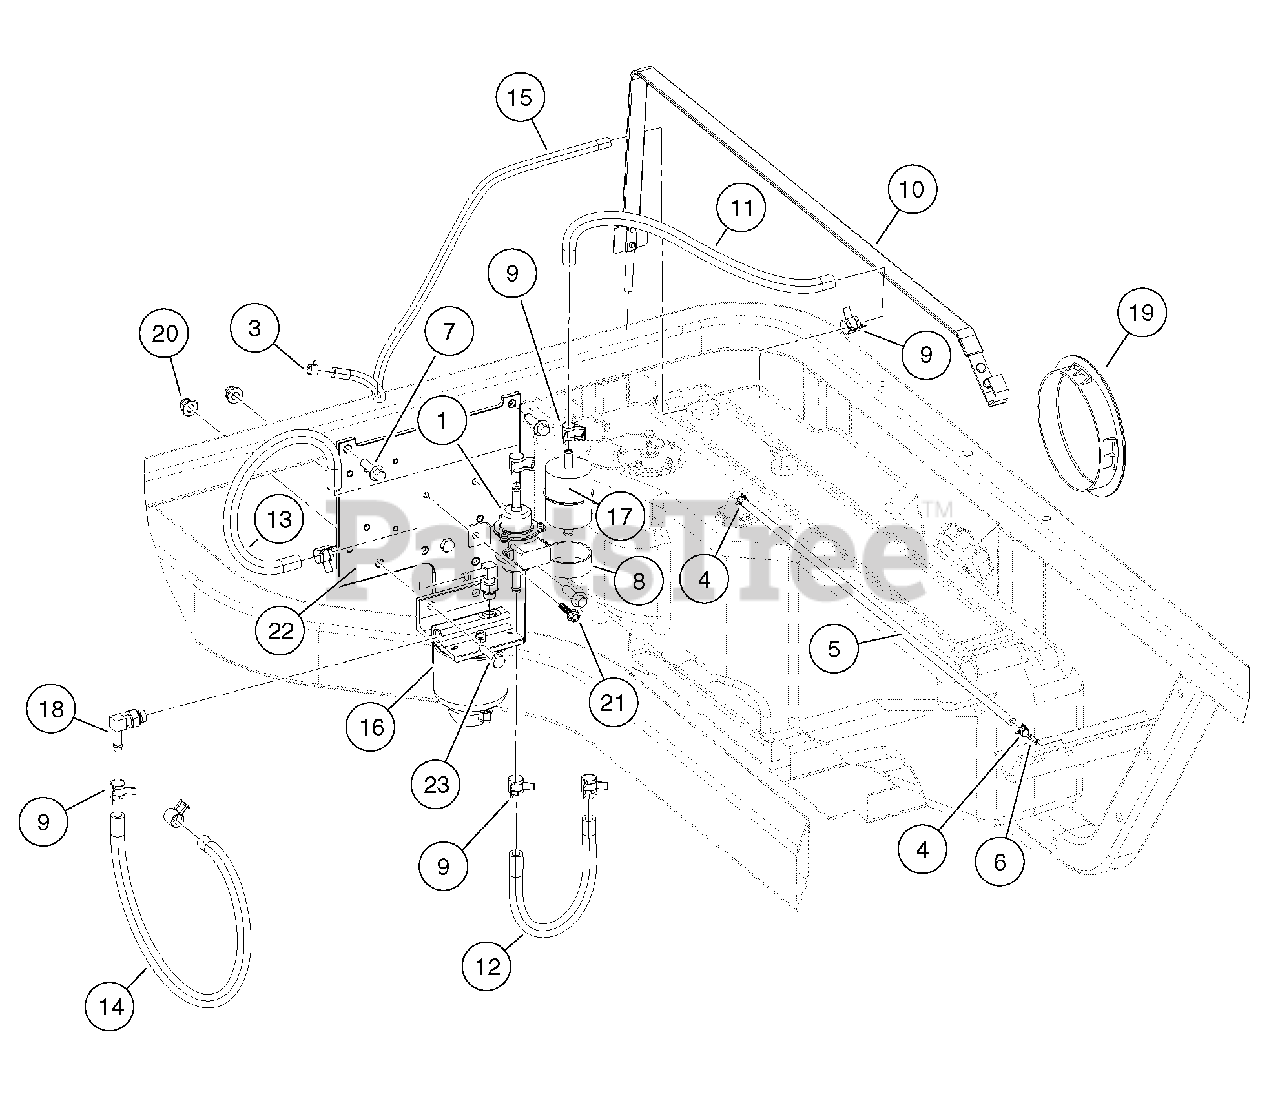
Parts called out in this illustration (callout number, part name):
1	Pump, Diesel Fuel Electric
2	Asm, Fuel System, Kubota
3	Clamp, Green Hose
4	Clamp, 0.301 ID Hose
5	Hose, Fuel, Vent, 22" Long
7	Screw, M8X1.25X30, Hex
8	P-Clamp, Insulated 1.75 In
9	Clamp, Hose, Ctb 14mm
10	Strap, Tank, Fuel
11	Hose, Tank To Prefilter Diesel
12	Hose, Fuel Prefilter To Pump
13	Hose, Fuel Pump To Filter
14	Hose, Fuel Filter To Eng
15	Hose, Fuel Return
16	Filter Assy, Fuel
17	Filter, Fuel
18	Adapter, 90, 5/16 Tube
19	Bezel, Fuel Fill
20	Lock Nut, Flg M8 X 1.25 Nylon
21	Screw, M6 X 1 X 25 Thd Form
22	Plate, Fuel/Oil System
23	Bolt, M8 X 1.25 X 30
